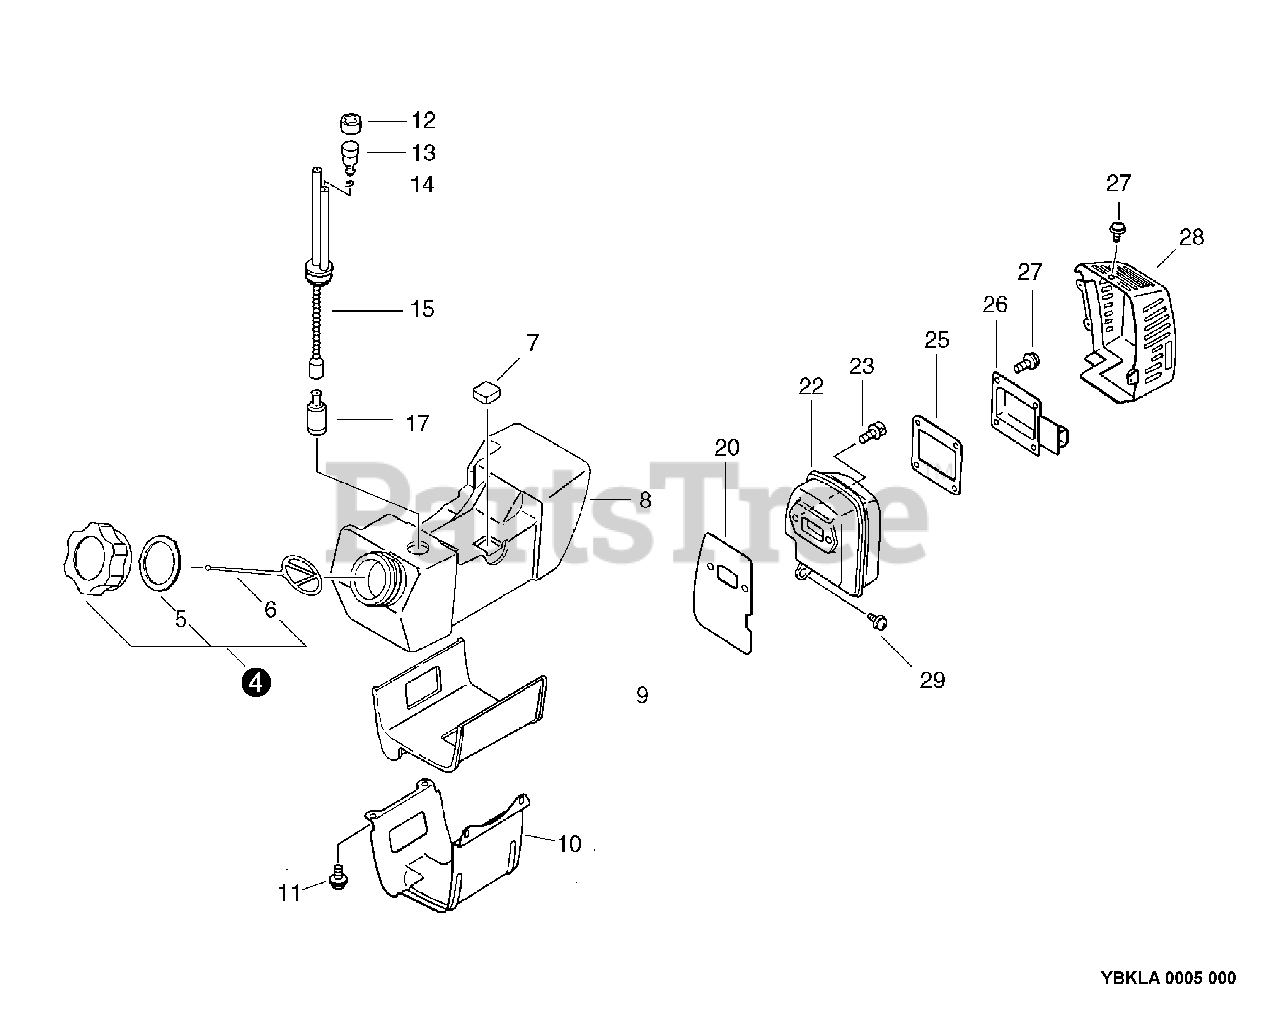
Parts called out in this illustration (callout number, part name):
4	CAP ASSY, FUEL
5	GASKET, FUEL CAP
6	CONNECTOR, CAP L= 100 MM
8	TANK, FUEL
10	BRACKET, FUEL TANK
11	SCREW 5×14
12	HOLDER, VENT
13	VENT ASSY
14	CLIP Ø6.5 MM
15	PIPE, FUEL
17	FILTER, FUEL
20	GASKET, MUFFLER
23	BOLT 5×20
25	GASKET, EXHAUST
26	GUIDE, EXHAUST
27	SCREW 4×10
28	COVER, MUFFLER
29	SCREW 5×14
